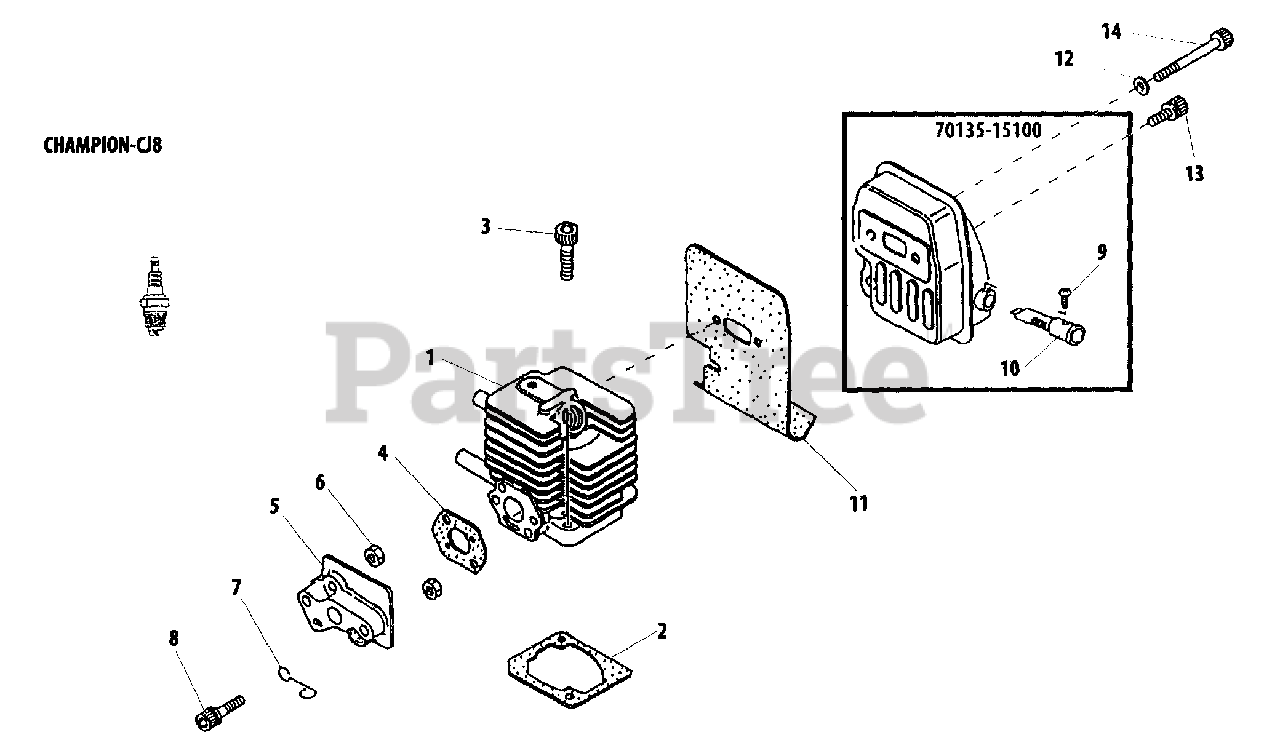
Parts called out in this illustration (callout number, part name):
1	CYLINDER
2	GASKET, CYLINDER
3	SCREW - 5X25
4	GASKET
5	INSULATOR
6	NUT
7	HOLDER, VENT
8	SCREW - 5X25
9	SCREW - 3X6
10	SCREEN, SPARK ARRESTOR
11	SHIELD, EXHAUST
12	WASHER - 5
13	SCREW - 5X12
14	SCREW - 5X50
70135-15100	MUFFLER ASSY
